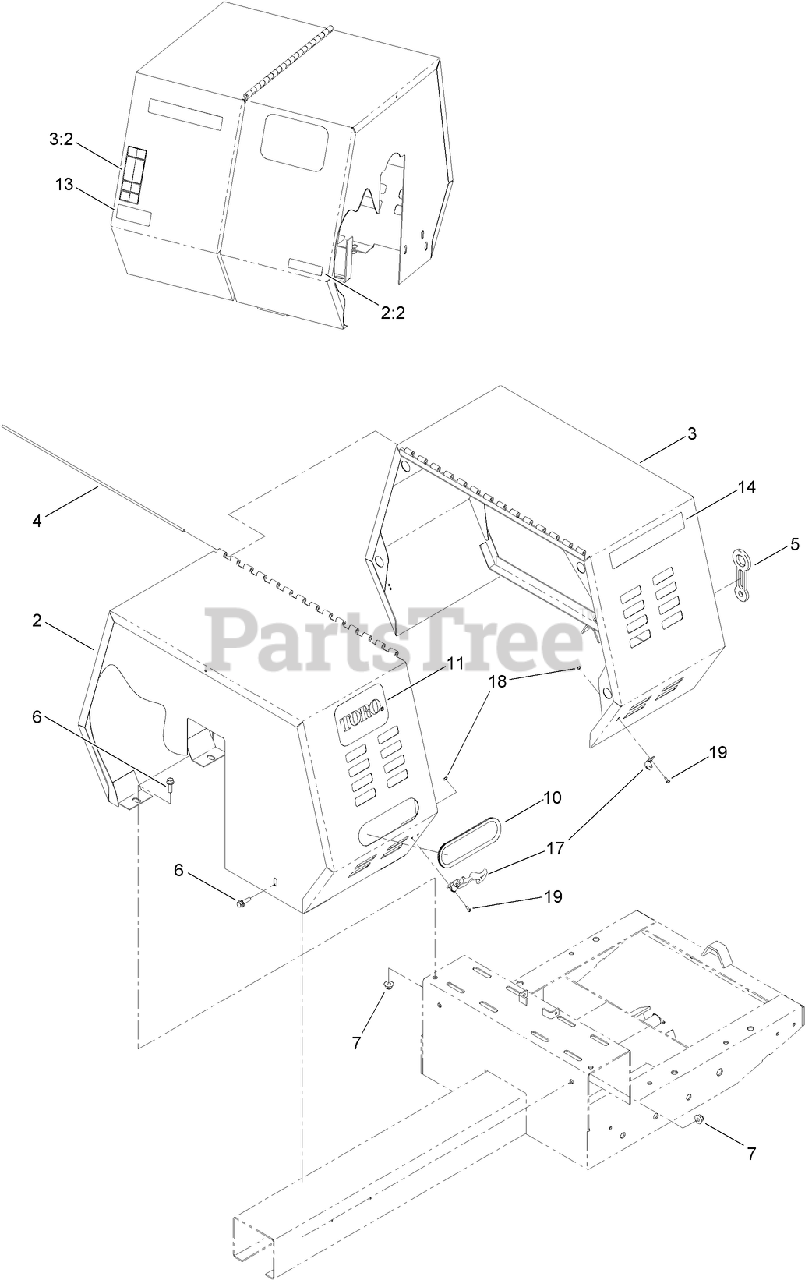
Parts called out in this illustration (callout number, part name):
2	STATIONARY COWL ASM
2:2	DECAL-ARRESTER, SPARK
3	MOVABLE COWL ASM
3:2	DECAL-WARNING
5	LATCH-RUBBER
6	SCREW-HHF
7	NUT-HF, NI
10	TRIM-LID
11	DECAL
14	DECAL-MM-12511H
17	LATCH-FLEX, DRAW
18	NUT-LOCK, NI
19	SCREW-HWH
